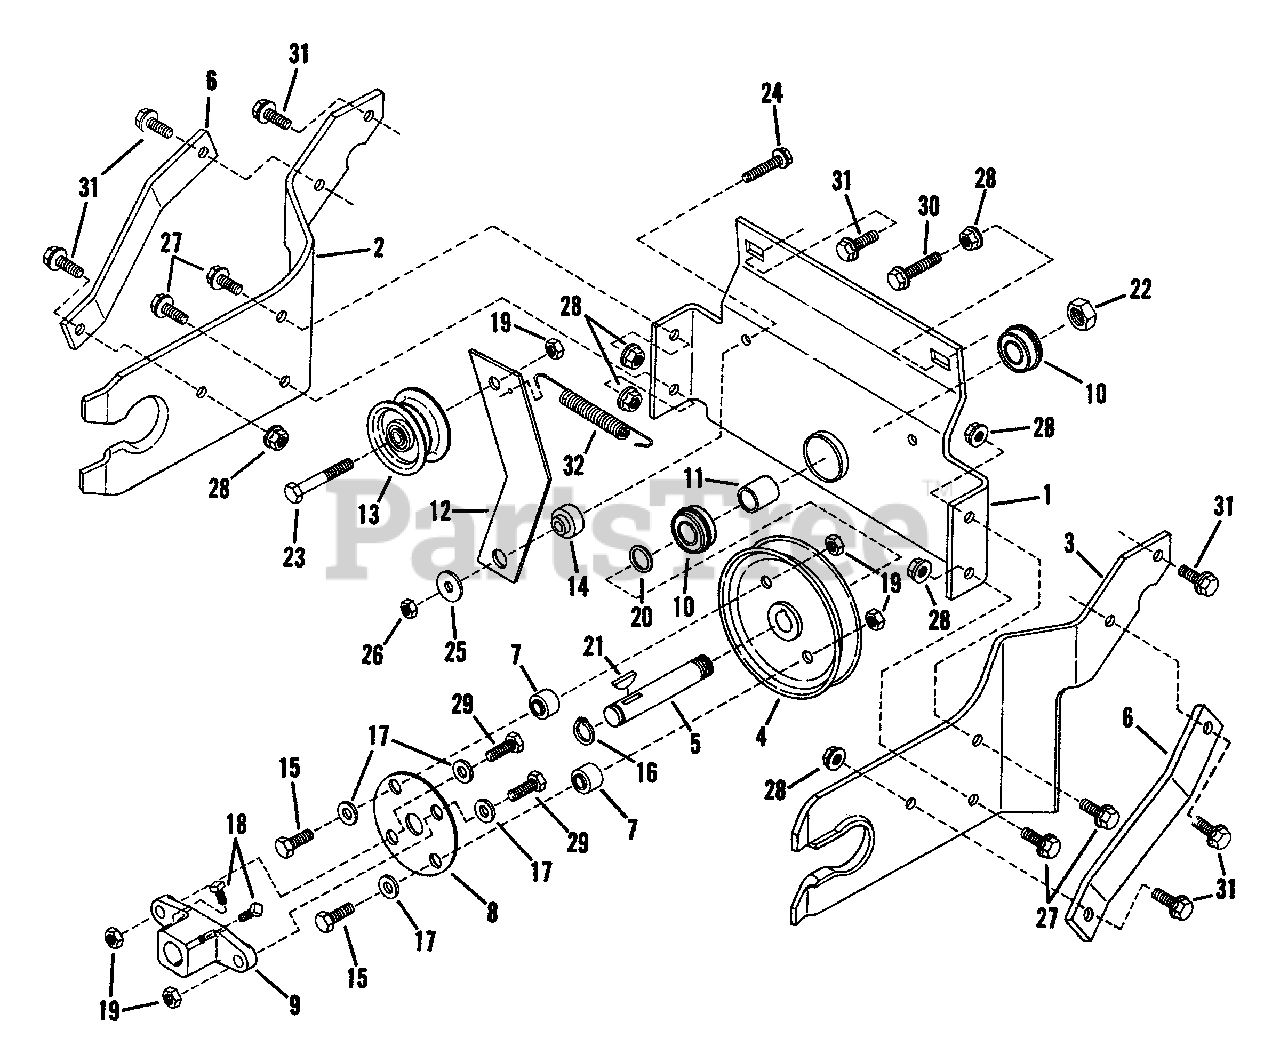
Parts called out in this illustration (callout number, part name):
1	WELDMENT, Hitch & Bearing
2	HITCH, Right Hand
3	HITCH, Left Hand
4	PULLEY, 5.25" O.D.
5	SHAFT, Pulley
6	STRAP, Gusset
7	SPACER, Flex-Coupling
8	DISC, Flex-Coupling
9	HUB, Flex-Coupling
10	BEARING, Ball
12	ARM, Idler
13	IDLER, 2.50" O.D.
14	SPACER, Shoulder
15	SCREW, 3/8-16x1-1/4" Hex Head Cap
16	RING, 5/8" External Retaining
17	WASHER, 3/8" Flat
18	SCREW, 5/16-18x1/2" Square Head Set
19	NUT, 3/8-16 Hex Lock
20	WASHER, Shim
21	KEY, (#6) 5/32 x 5/8" Woodruff
22	NUT, 5/8-18 Hex Lock
23	SCREW, 3/8-16x1-1/2" Hex Head Cap
24	SCREW, 5/16-18x1-1/4" Hex Head Cap
25	WASHER, 5/16 Flat
26	NUT, 5/16-18 Hex Flange Lock
27	BOLT, 3/8-16x3/4" Hex Flange Lock
28	NUT, 3/8-16 Hex Flange Lock
29	SCREW, 3/8-16x1" Hex Head Cap
30	SCREW, 3/8-16x1-1/4" Hex Head Cap
31	BOLT, 3/8-16x7/8" Hex Flange Lock
32	SPRING, Idler
